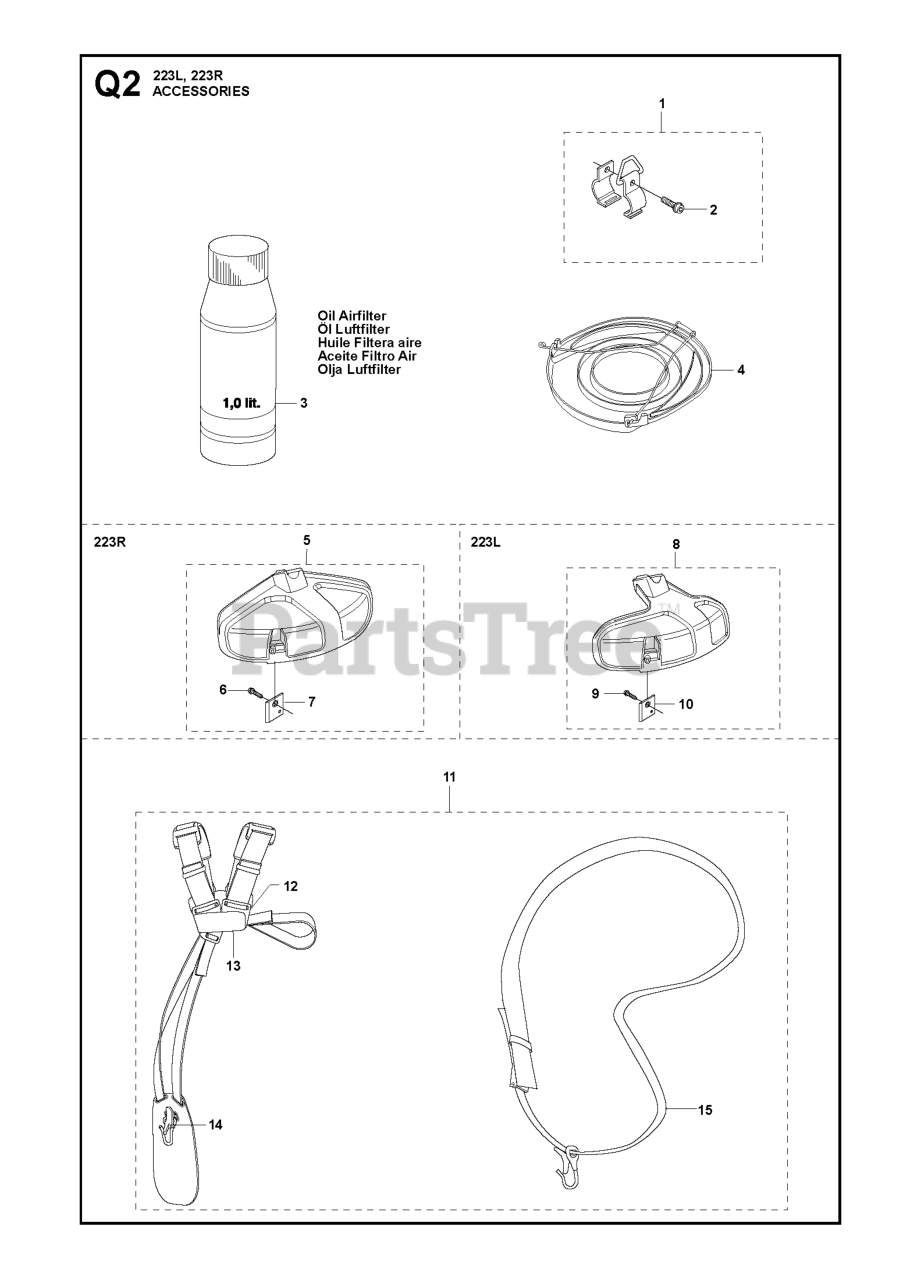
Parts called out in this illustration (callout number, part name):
1	HANGING BKT SHOULDER HARNESS
2	SCREW 5X14
3	Air Filter Oil 1l.
4	BLADE GUARD TRANSPORT
5	GRASS SHIELD
7	LINE CUTTER
8	TRIMMER GUARD ASSEMBLY
10	LINE CUTTER
11	HARNESS DUO
11	Harness w/warning
14	HOOK, CPL.
15	Harness-w/o warning
15	Harness - Diagonal with sign
